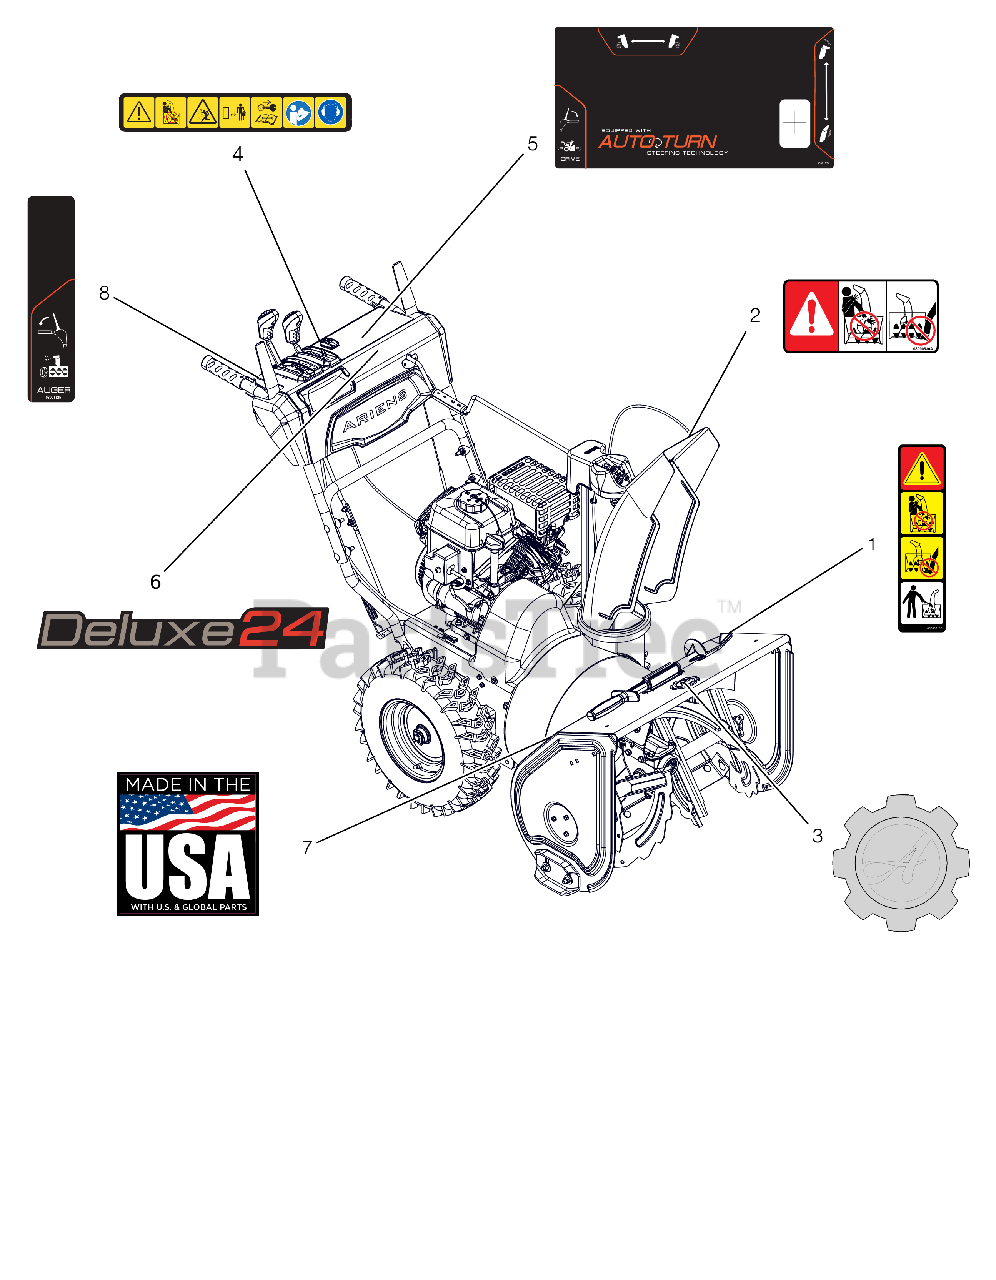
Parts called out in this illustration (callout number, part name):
1	DECAL, DANGER - ROTATING PARTS
2	DECAL, DANGER
3	DECAL, ARIENS-GEAR BADGE -THK
4	DECAL,DASH - SAFETY
5	DECAL,CONTROL-LG ID
6	DECAL, DASH - DELUXE 24
7	DECAL, MADE IN USA
8	DECAL,CONTROL-RH CONTROL
